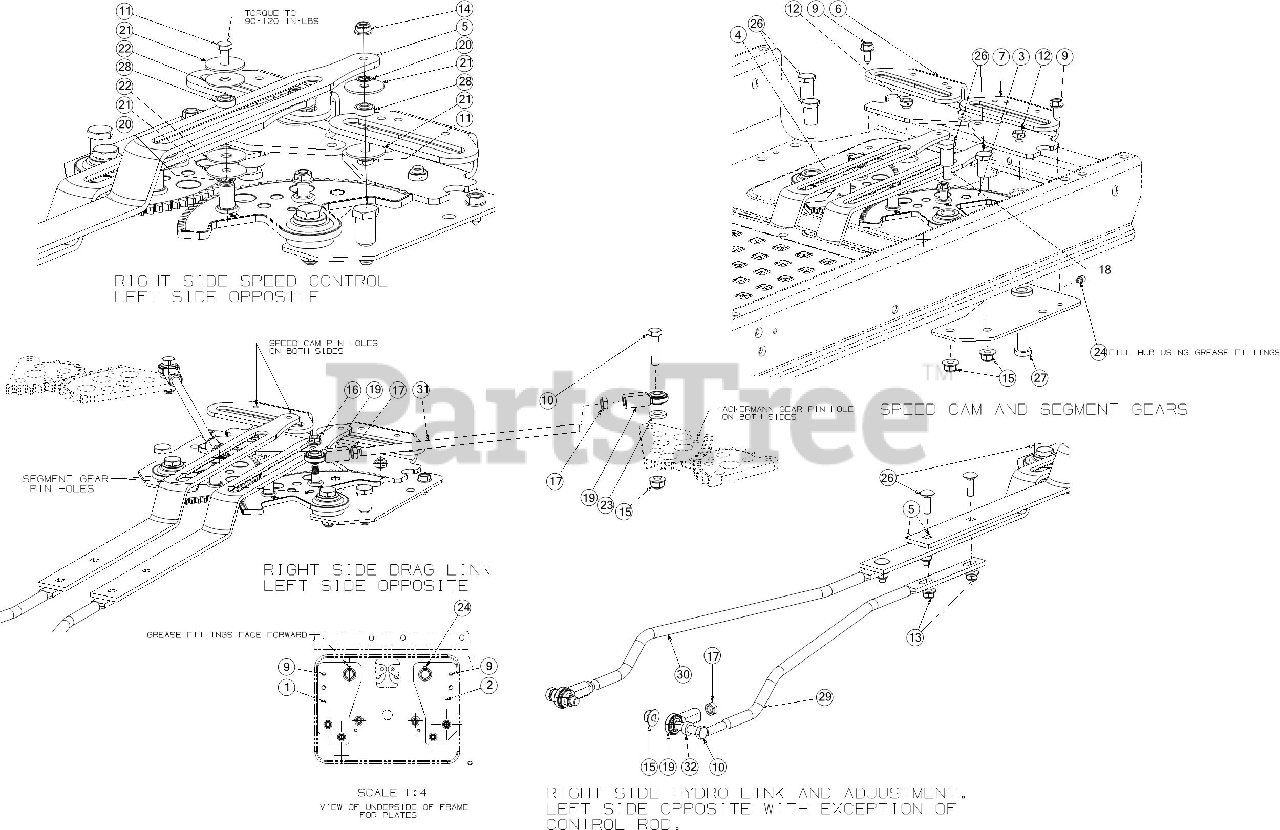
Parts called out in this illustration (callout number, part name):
1	STEERING SUPPORT PLATE (RH)
2	STEERING SUPPORT PLATE (LH)
3	STEERING GEAR ASSEMBLY (LH)
4	STEERING GEAR ASSEMBLY (RH)
5	HYDRO CONTROL LINK
6	SPEED CAM PLATE (LH)
7	SPEED CAM PLATE (RH)
8	CARRIAGE BOLT 5/16-18 X 1.00
9	SCREW 5/16-18 X .750
10	SCREW 3/8-16 X 1.50
11	SCREW 1/4-20X1.0 GR5
12	JAM LOCK NUT
13	FLANGE LOCK NUT 5/16-18
14	FLANGE LOCK NUT
16	FLANGE NUT
17	HEX JAM NUT 3/8X24
18	LOCTITE
19	BALL JOINT-(RH)
20	RETAINER-BOLT .25ID x .50OD
21	FLAT WASHER
22	WASHER .355X1.25X.048THK
23	FLAT WASHER
24	GREASE FITTING
26	SHOULDER SCREW .625 X .875 X 3/18
27	SHOULDER SCREW .50
28	BALL BEARING .25 X .625 SPCL
29	HYDRO LINK ROD (RH)
30	HYDRO LINK ROD (LH)
31	STEERING DRAG LINK
32	SPACER-.380 ID X.625 OD X .227
